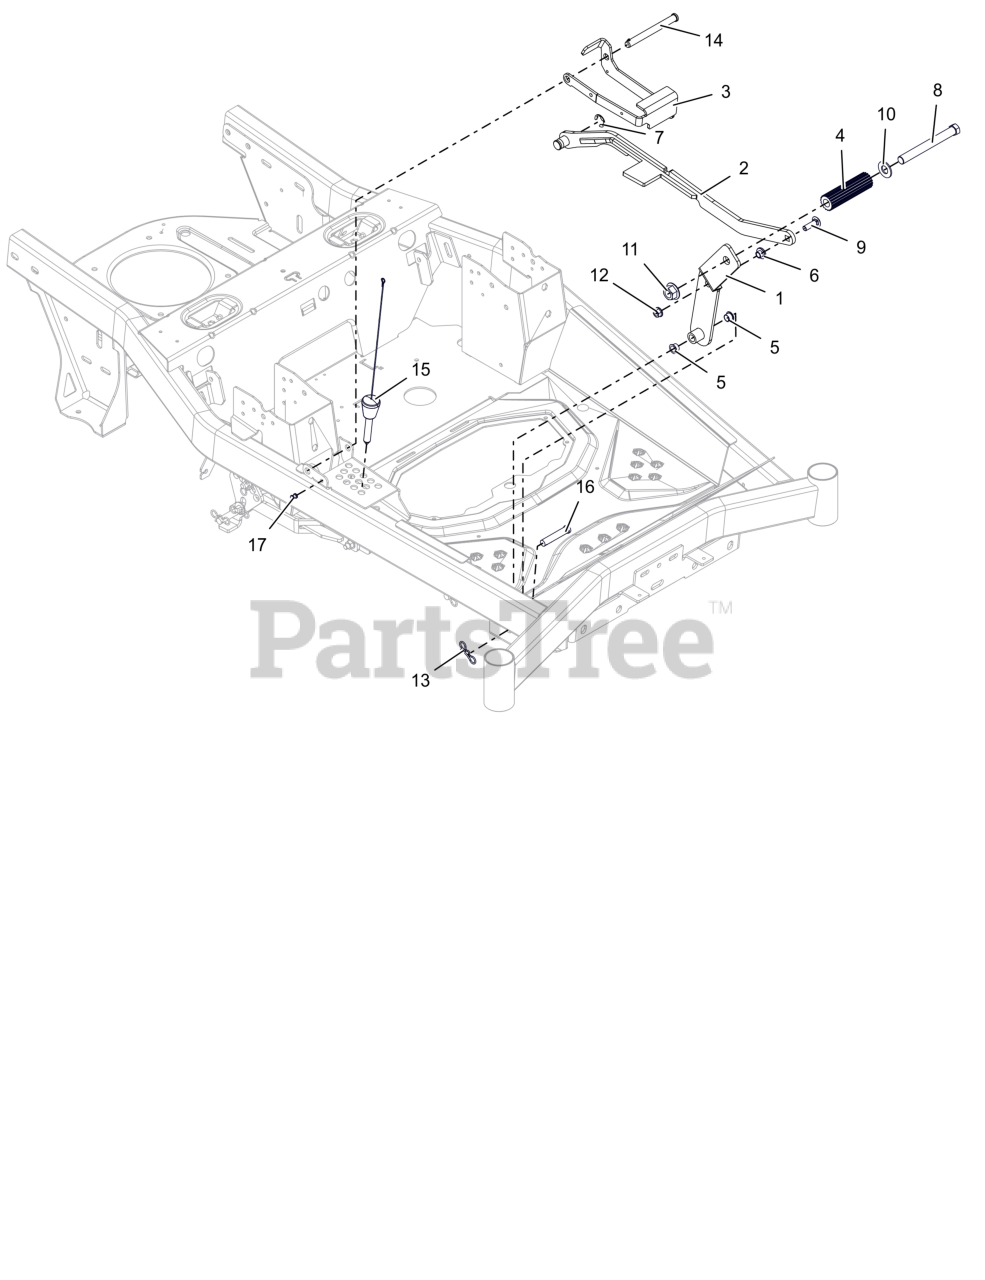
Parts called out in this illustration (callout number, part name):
1	WLDMT- FOOT PEDAL-ORG
2	LINK- DECK LIFT-ORG
3	WLDMT, TRANSPORT LOCK (ORANGE)
4	ROD, FOOT PEDAL (BLACK)
5	BUSHING, POLYLINER-.50 SPLIT
6	BSHG-FLG .385X.500X.875X.406
7	E-RING .750X.050
8	BLT, HEX .62-11X5.50 G5 FBP
9	BLT,RHSSN .38-16X1.25 G5 ZCC
10	WSHRFLT 5/8SAE CARBHARD FBP
11	NUT,FLG-TOP LK .625-11 FBP
12	NUT-LK-CTR-FLG .375-16 GF ZCC
13	PIN, BOWTIE .091X1.875 ZCC
14	PIN-SLIC .50X4.97X4.55 -ZCC
15	PIN- MAGNETIC .50X2.70
16	PIN-CLEV .494X2.50 BRIGHT ZINC
17	POST, & SCREW, PUSH LOCK .25 X .25
